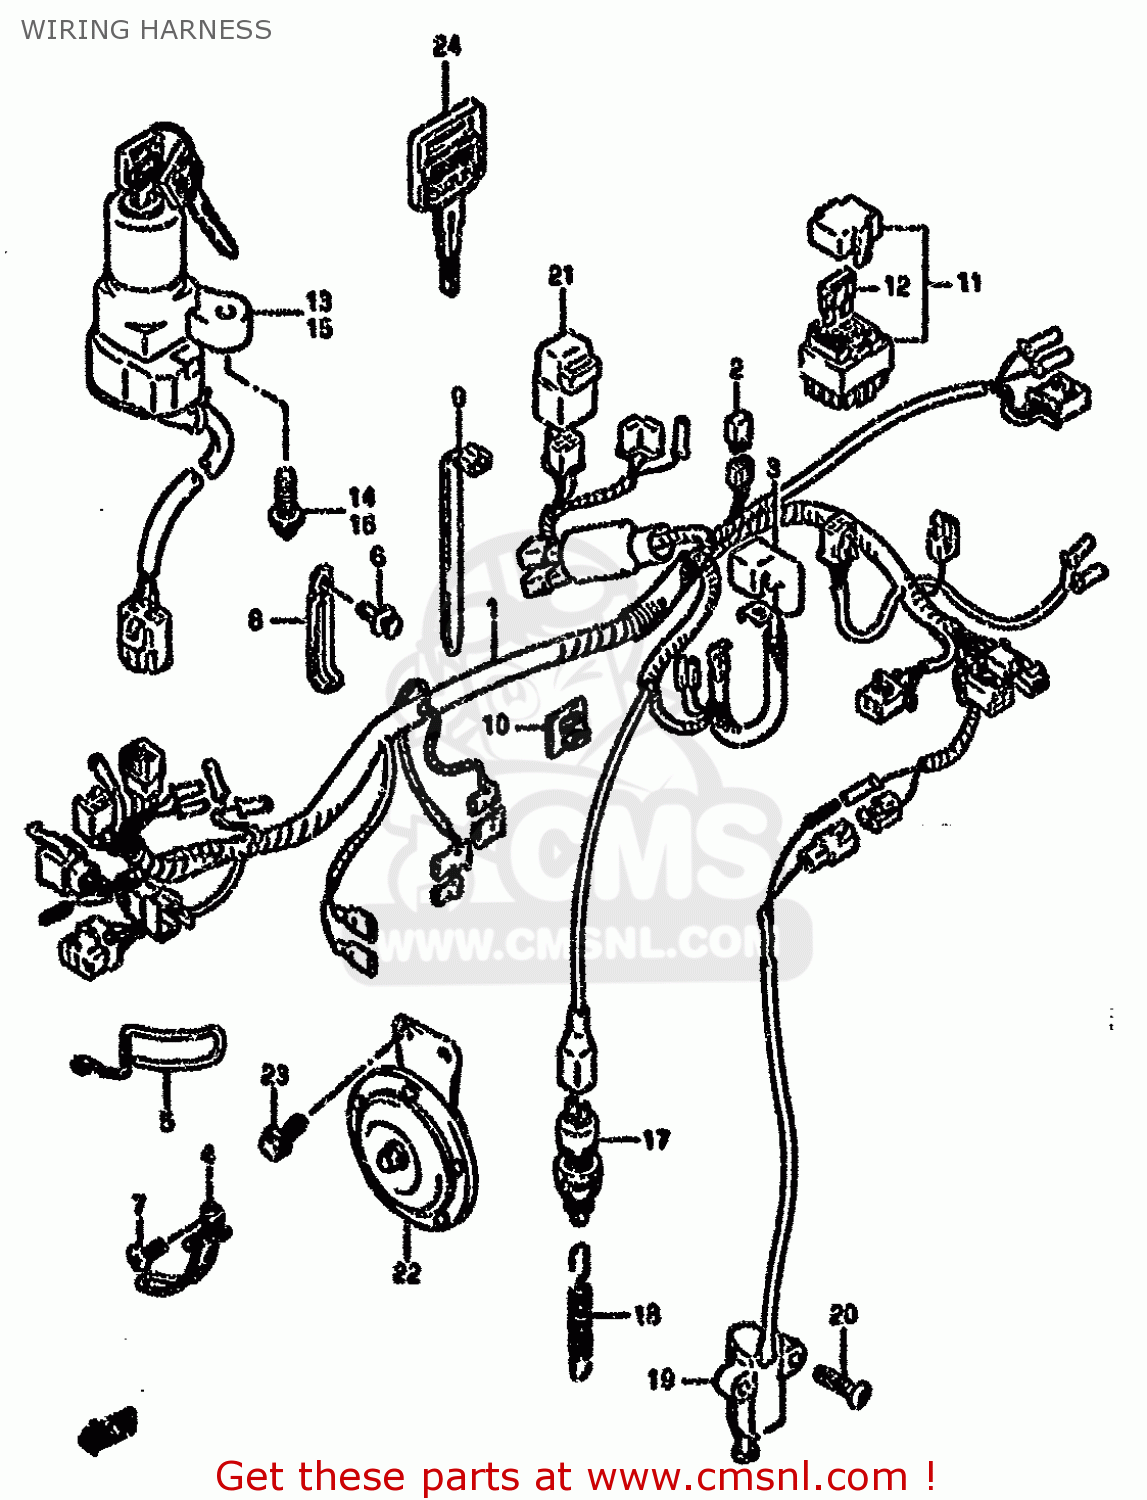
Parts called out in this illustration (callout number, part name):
1	HARNESS,WIRING
2	DIODE(STANLEY DE8804)
3	CAP,BATTERY PLUS
4	PROTECTOR
5	PROTECTOR
6	CLIP
7	SCREW 6X12
8	CLAMP
9	CLAMP L:165
10	CLAMP
11	BOX ASSEMBLY,FUSE
12	FUSE(20A)
13	LOCK ASSEMBLY,STEERING
14	SCREW(6X18)
15	LOCK ASSEMBLY,STEERING
16	SCREW(6X18)
17	SWITCH ASSY,STOP LAMP
18	SPRING
19	SWITCH ASSY,SIDE STAND
20	BOLT
21	RELAY ASSY
22	HORN ASSY
23	BOLT
24	KEY,BLANK
